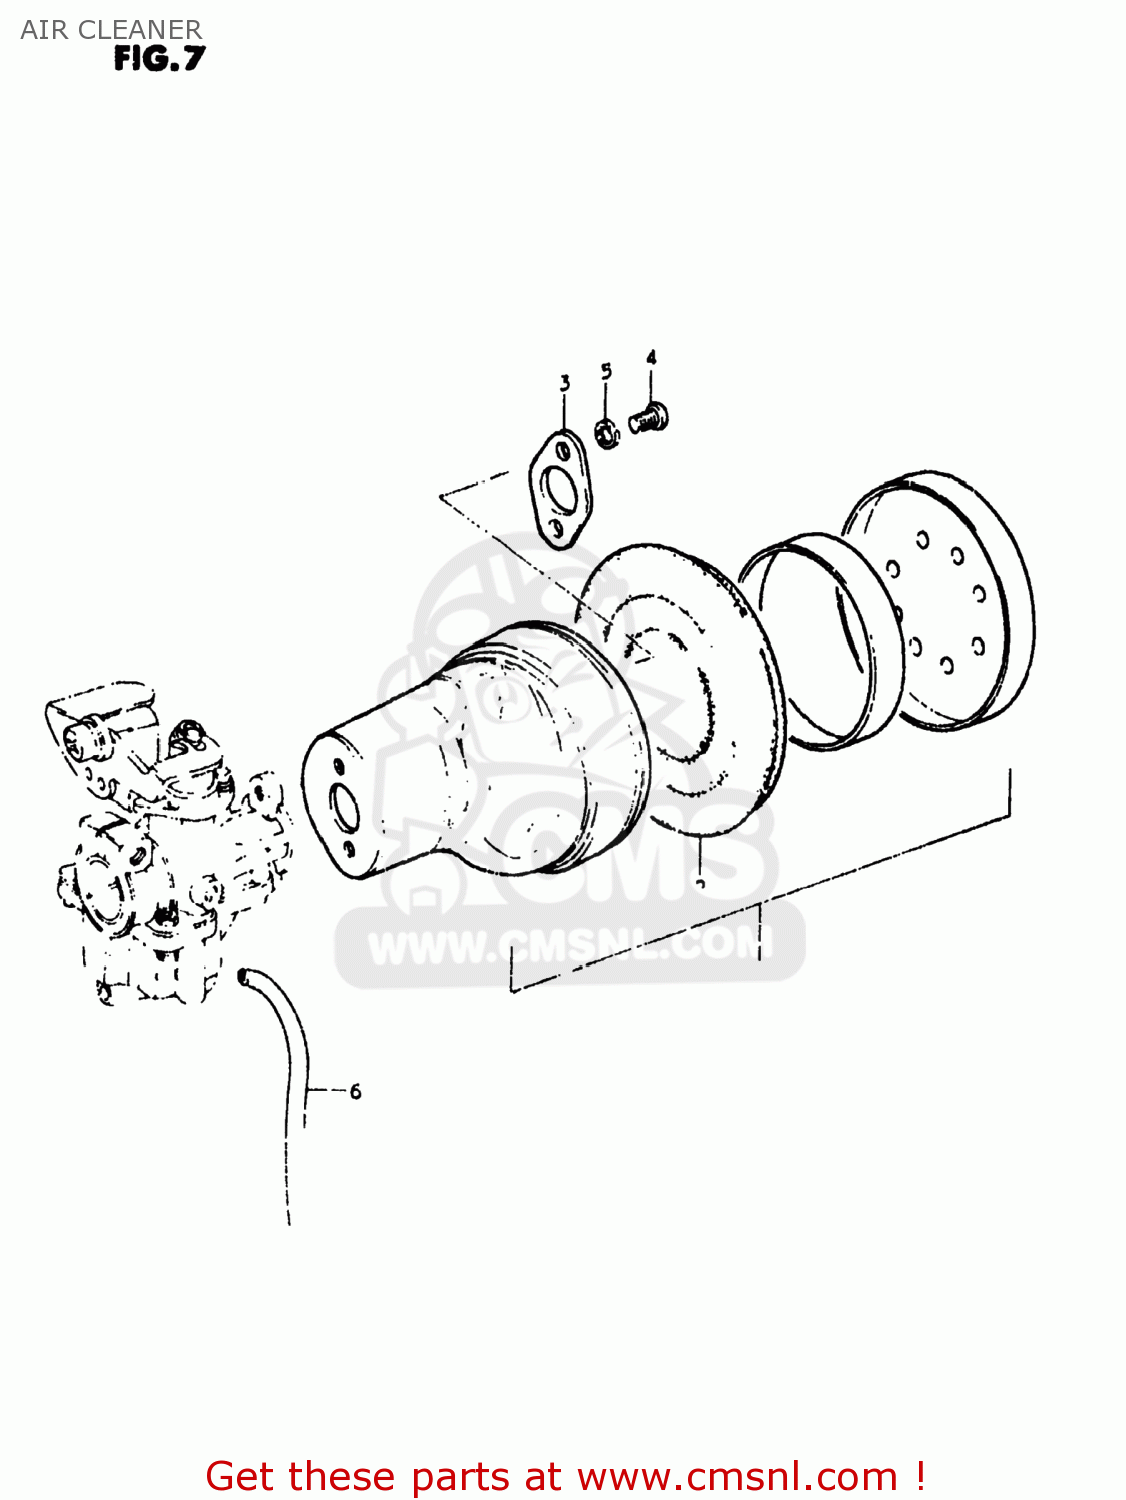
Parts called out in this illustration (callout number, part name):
1	CLEANER ASSY,AIR
2	FILTER,AIR CLEANER
3	PLATE,AIR CLEANER
4	SCREW
5	LOCK WASHER
6	HOSE
